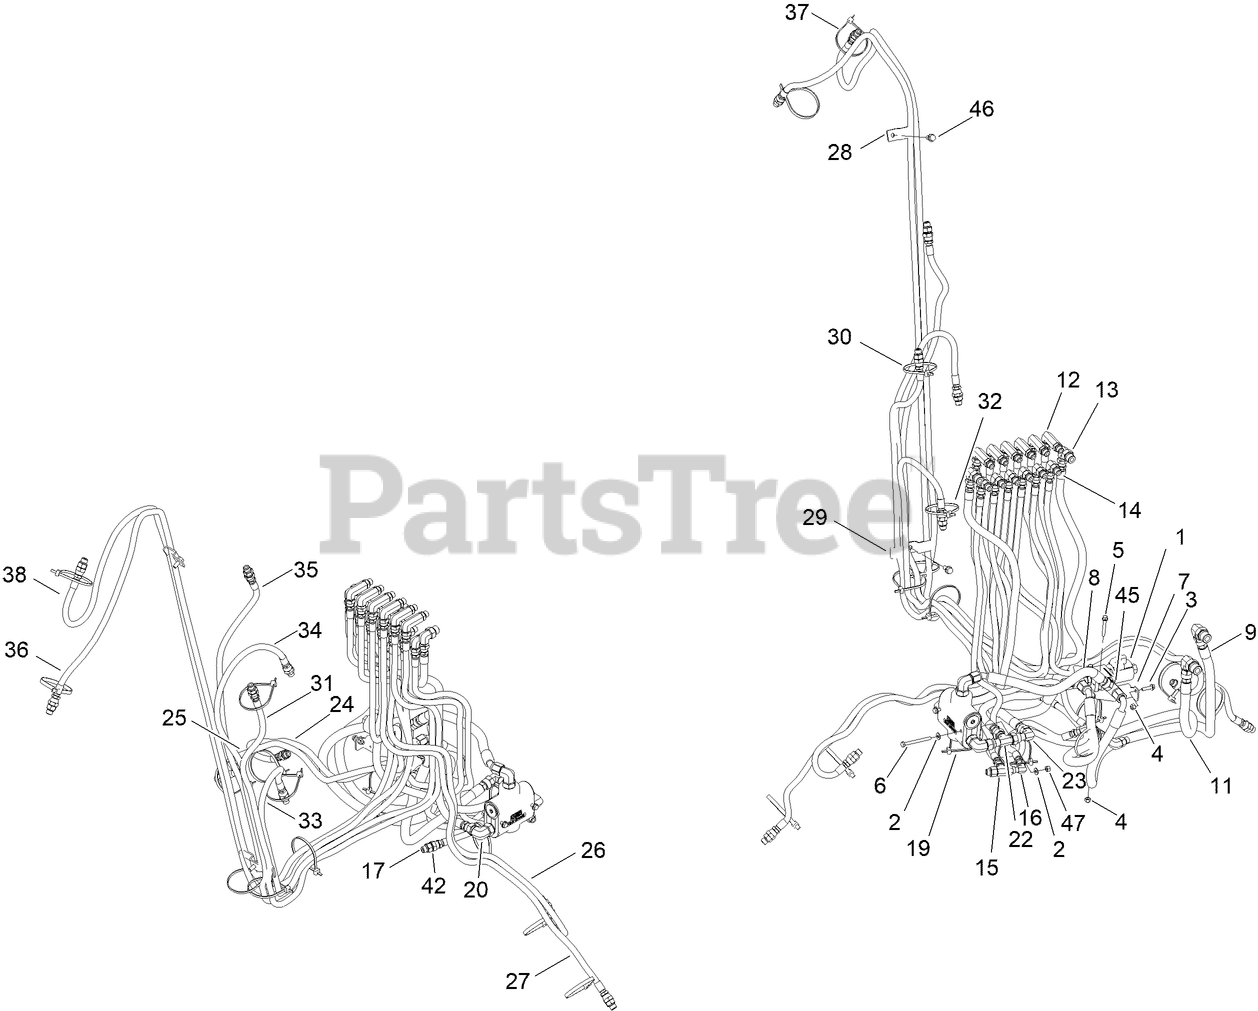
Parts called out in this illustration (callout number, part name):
1	HYD MANIFOLD ASM
1:1	HOUSING
2	WASHER
3	SCREW-HHF
4	NUT-HEX
5	SCREW-HHF
6	SCREW-HH
7	BRACKET-MOUNT, VALVE
8	HYD HOSE ASM
9	HYD HOSE ASM
11	HOSE HYD ASM
12	FITTING-HOSE
13	FITTING-HOSE
14	FITTING-HOSE
15	FITTING-HOSE
16	FITTING-HOSE
17	FITTING-HOSE
19	VALVE-HYDRO
20	FITTING-HOSE
22	FITTING-HOSE
23	FITTING-HOSE
24	HOSE-HYDRO
25	HOSE-HYDRO
26	HOSE-HYDRO
27	HOSE-HYDRO
28	RETAINER-HOSE
29	RETAINER-HOSE
30	TIE-HYDRO
31	HOSE-HYDRO
32	TIE-HYDRO
33	HOSE-HYDRO
34	HOSE-HYDRO
35	HOSE-HYDRO
36	HOSE-HYDRO
37	TIE HYDRO
38	HOSE-HYDRO
42	HOSE-HYDRO
45	FITTING-TEE
46	SCREW-HHF
47	NUT-HEX, SIDE DEFORM
